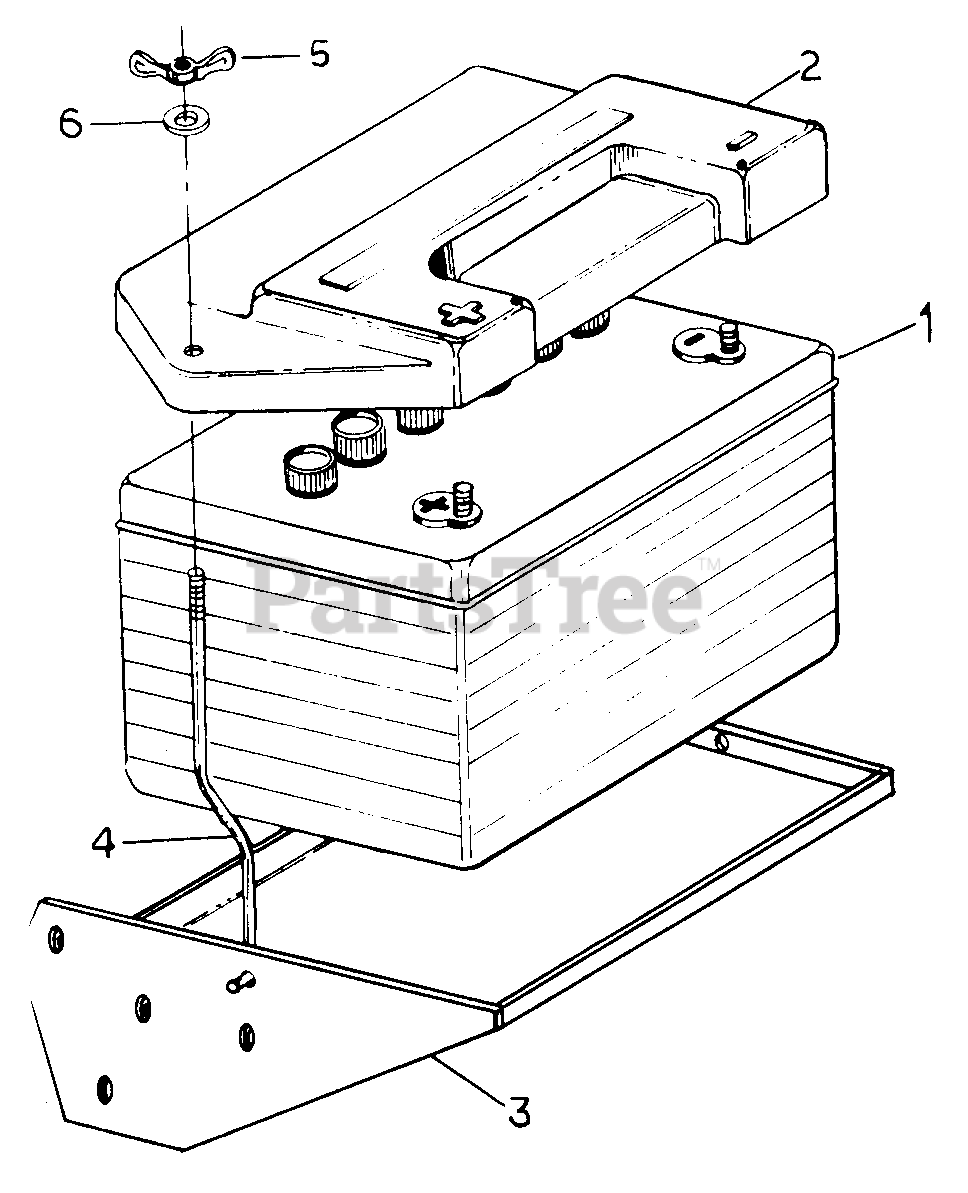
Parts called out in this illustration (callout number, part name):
2	Cover, Battery w/Product Graphic
3	Tray, Battery
4	Rod, Battery Cover
5	Nut, 1/4 Wing
6	Washer, .281 X .500 X .056 Pln
